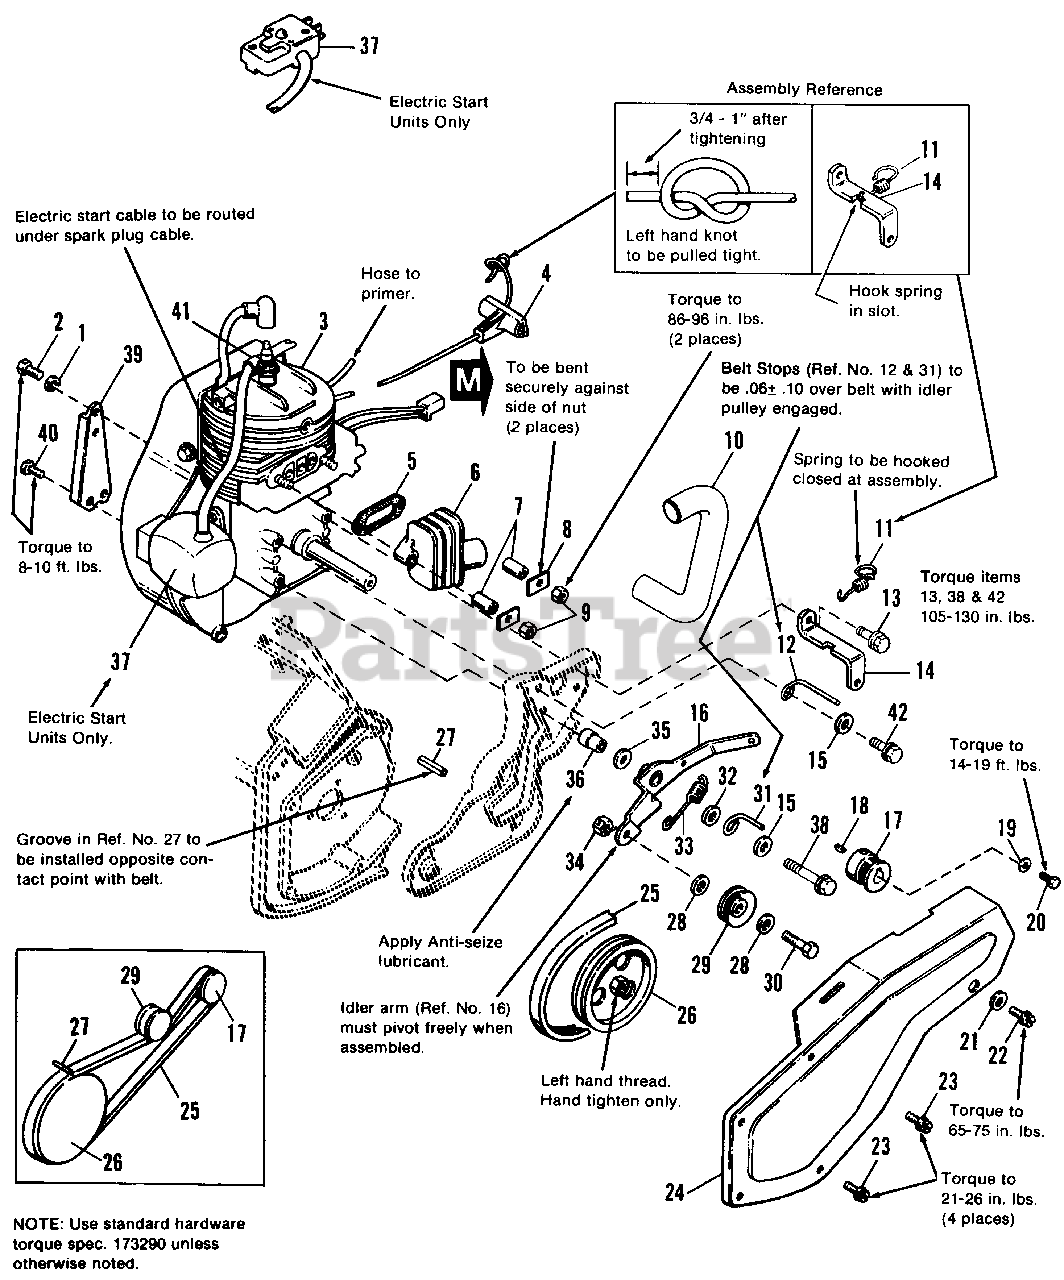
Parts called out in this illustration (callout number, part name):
1	LOCKWASHER, 1/4
2	CAPSCREW, Hex Hd., 1/4-20 x 3/8
4	HANDLE, Pull
5	GASKET, Manifold
6	MANIFOLD, Exhaust
8	KEEPER-NUT
9	LOCKNUT, Hex, 1/4-20
10	PIPE, Exhaust
11	SPRING, Extension
12	STOP, Belt
13	SCREW, Hex, Whizlock, 5/16-18 x 5/8
14	BRACKET, Cover
15	WASHER, Plain, 5/16
16	ARM ASSY., Idler
17	PULLEY, Drive
18	KEY, Woodruff, 5/32 x 5/8
19	LOCKWASHER, 5/16
20	CAPSCREW, Hex Hd., 5/16-24 x 3/4
21	WASHER, Shakeproof #10
22	SCREW, Wash. Hd., Hex, Slotted, #10-14 x 5/8
23	SCREW, Wash. Hd., Hex, Slotted, #10-14 x 1/2
24	COVER, Belt
25	BELT, Drive
26	PULLEY, Drive
27	GUIDE, Belt
28	WASHER, Plain, 3/8
29	PULLEY, Idler
30	CAPSCREW, Hex Hd., 3/8-16 x 1-1/4
31	STOP, Belt
32	WASHER, Plain, 5/16
33	SPRING, Tension
34	LOCKNUT, Hex, Center, 3/8-16
37	KIT, Electric Start
38	SCREW, Hex, Whizlock, 5/16-18 x 2-1/4
39	BRACKET, Engine
40	SCREW, Hex, Taptite, 1/4-20 x 1/2
41	CLIP, Tinnerman (Used on E.S. only)
42	SCREW, Hex, Whizlock, 5/16-18 x 34
